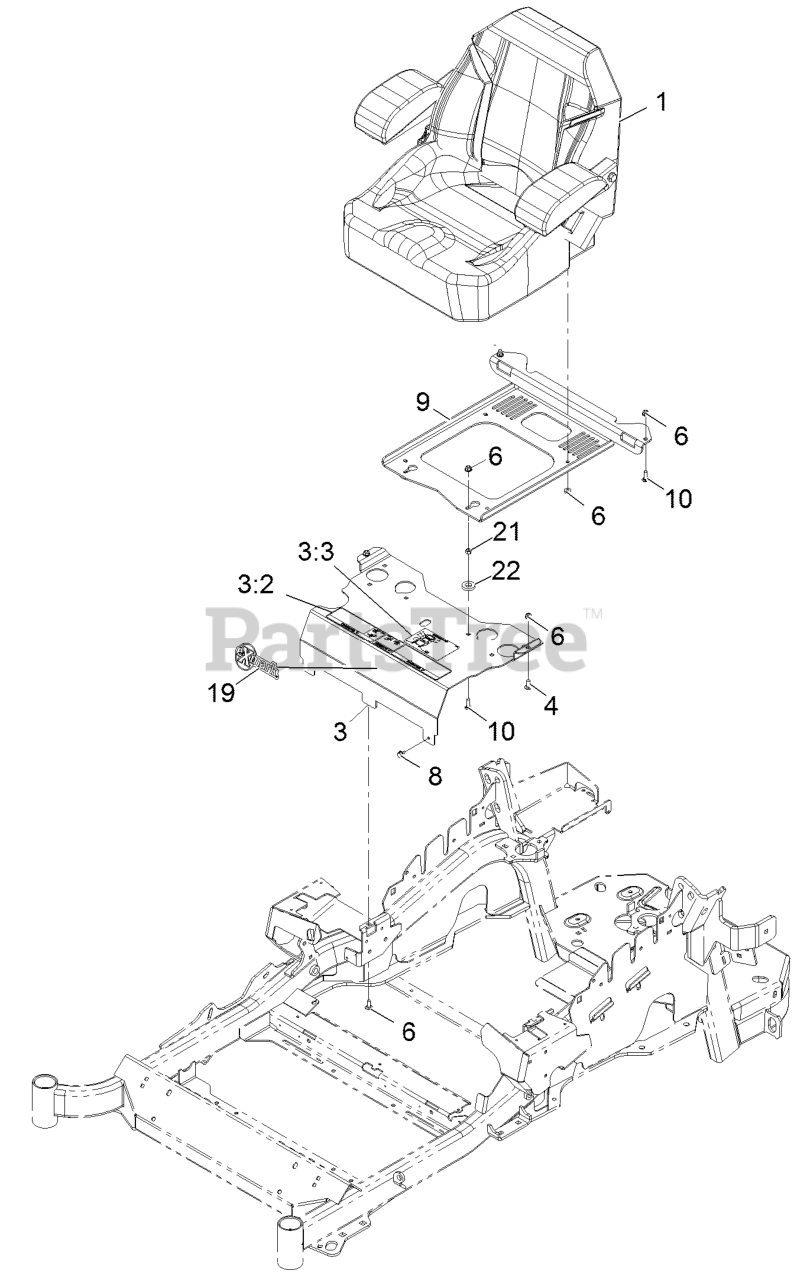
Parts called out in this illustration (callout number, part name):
3	MOUNT-SEAT
3:2	DECAL-CONSOLE
3:3	DECAL-SERVICE AID
4	SCREW-CARR
6	NUT-HF, NI
9	PLATE-SUPPORT, SEAT
10	SCREW-CARR
21	NUT-HEX
